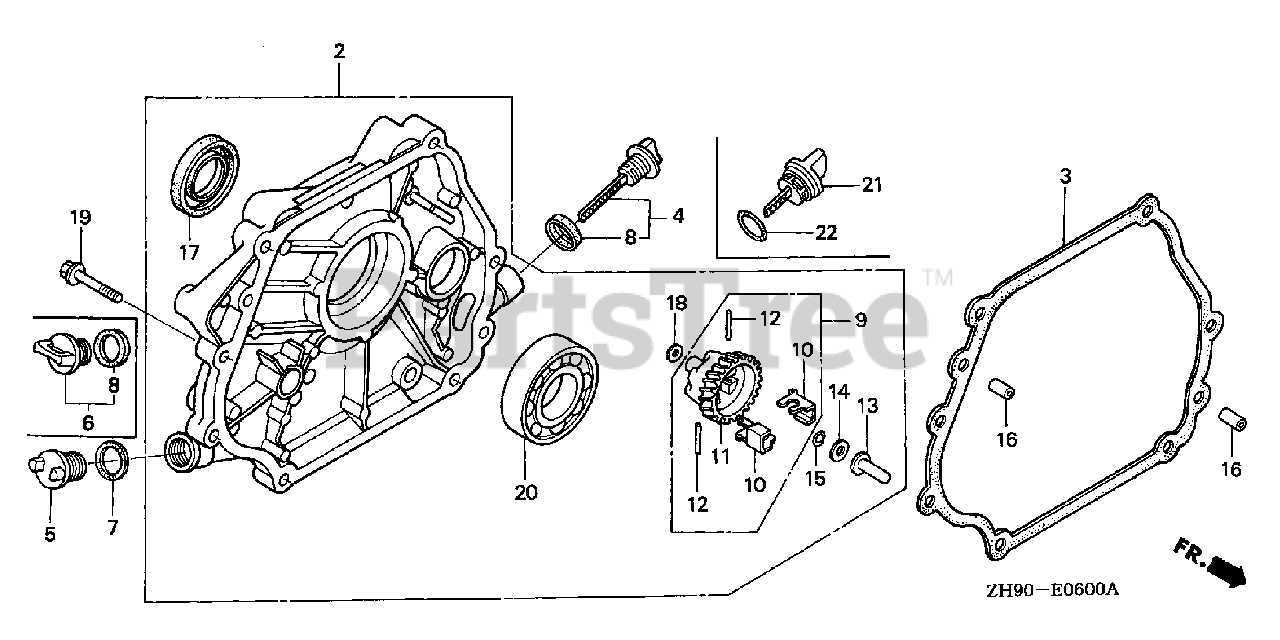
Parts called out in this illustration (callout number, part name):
2	COVER ASSY., CRANKCASE (Q-TYPE)
3	GASKET, CASE COVER
4	CAP ASSY., OIL FILLER
6	CAP ASSY., OIL FILLER
8	GASKET, OIL FILLER CAP
9	GOVERNOR ASSY. (STD)
10	WEIGHT, GOVERNOR
11	HOLDER, GOVERNOR WEIGHT
12	PIN, GOVERNOR WEIGHT
13	SLIDER, GOVERNOR
15	CLIP, GOVERNOR HOLDER
16	PIN, DOWEL (8X12)
17	OIL SEAL (30X46X8)
18	WASHER, PLAIN (6MM)
19	BOLT, FLANGE (8X35)
20	BEARING, RADIAL BALL (6206)
